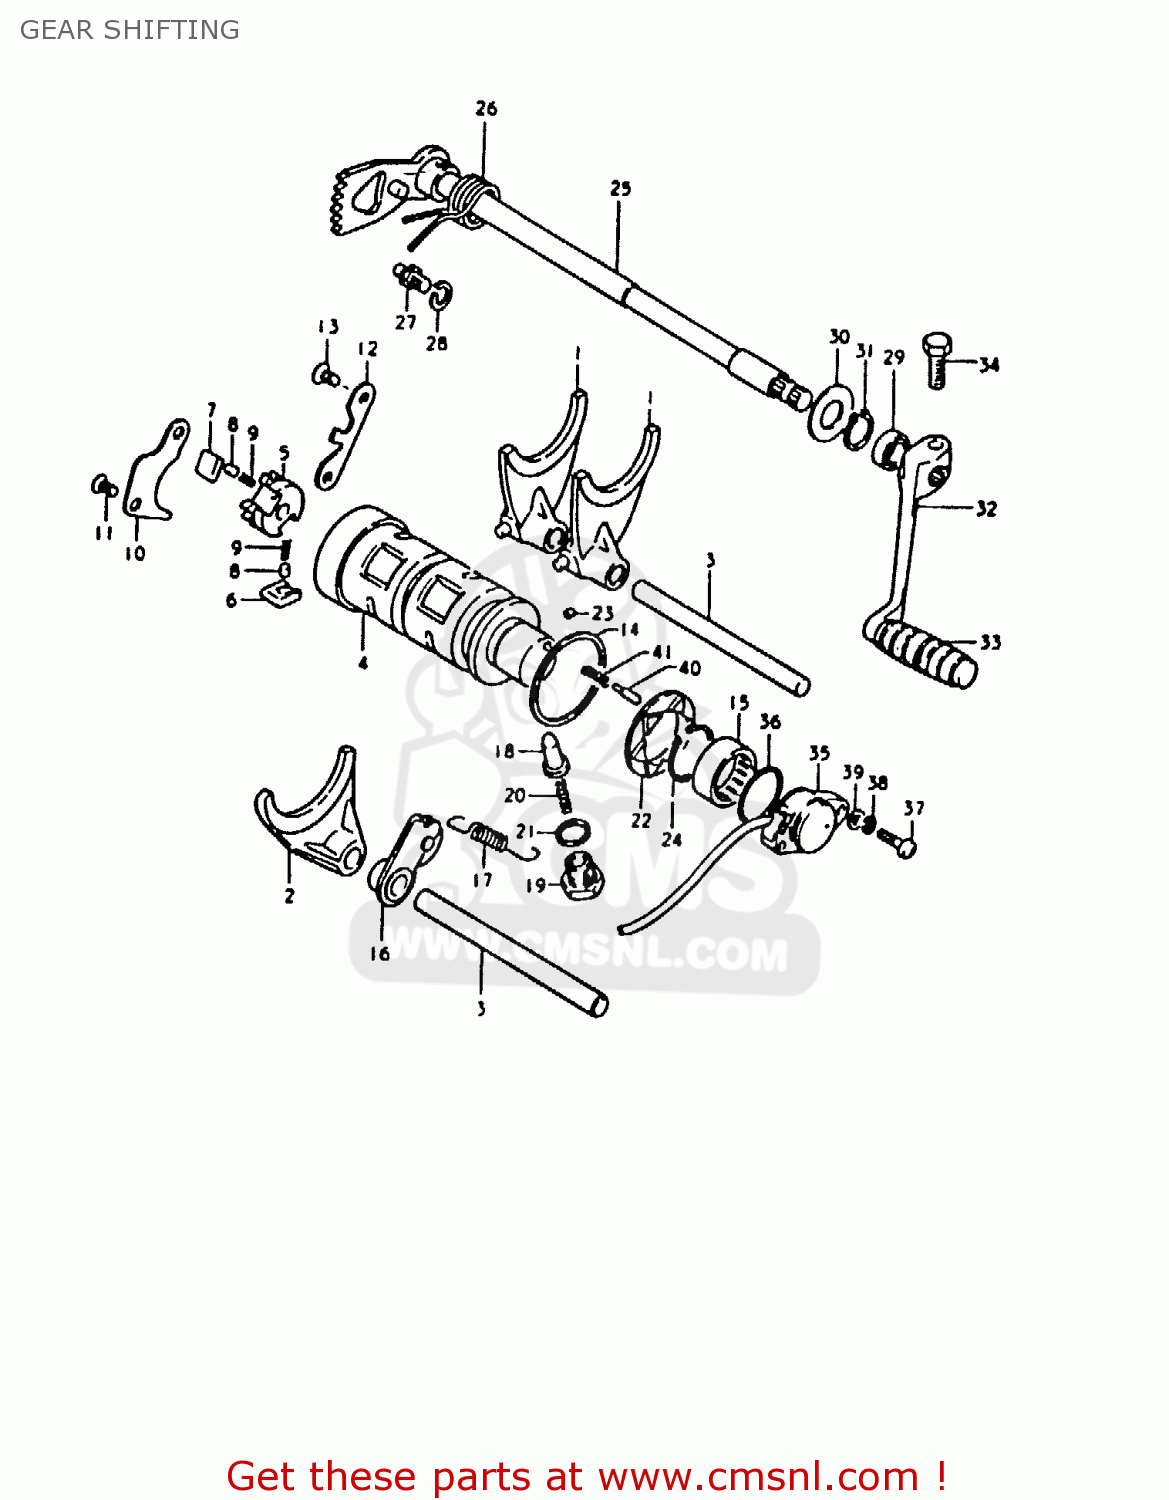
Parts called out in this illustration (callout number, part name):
1	FORK,GEAR SHIFT NO.1
2	FORK,GEAR SHIFT NO.3
3	SHAFT,GEAR SHIFT FORK
4	CAM,GEAR SHIFT
5	RETAINER,GEAR SHIFT CAM
6	PAWL,GEAR SHIFT NO.1
7	PAWL,GEAR SHIFT NO.2
8	PIN(5X8)
9	SPRING
10	LIFTER,GEAR SHIFT PAWL
11	SCREW
12	GUIDE,GEAR SHIFT CAM
13	SCREW
14	WASHER(40X45X1)
15	BEARING(25X32X12)
16	STOPPER,GEAR SHIFT CAM
17	SPRING
18	STOPPER,GEAR SHIFT CAM NO.2
19	HOLDER,GEAR SHIFT CAM STOP SPR
20	SPRING
21	GASKET(14X19.2X2) (NAS)
22	PLATE,GEAR SHIFT CAM STOPPER
23	PIN 4X6
24	CIRCLIP
25	SHAFT,GEAR SHIFT
26	SPRING
27	STOPPER,GEAR SHIFT CAM
28	WASHER
29	OIL SEAL
30	WASHER (12.5X27X1.6)
31	SPRING,RETAINER
32	LEVER ASSY,GEAR SHIFT
33	RUBBER,GEAR SHIFT PEDAL
34	BOLT
35	TERMINAL BASE,NEUTRAL SWITCH
36	O-RING (D:2.4 ID:26.2)
37	SCREW 5X20
38	LOCK WASHER
39	WASHER
40	PIN(5X15.5)
41	SPRING
